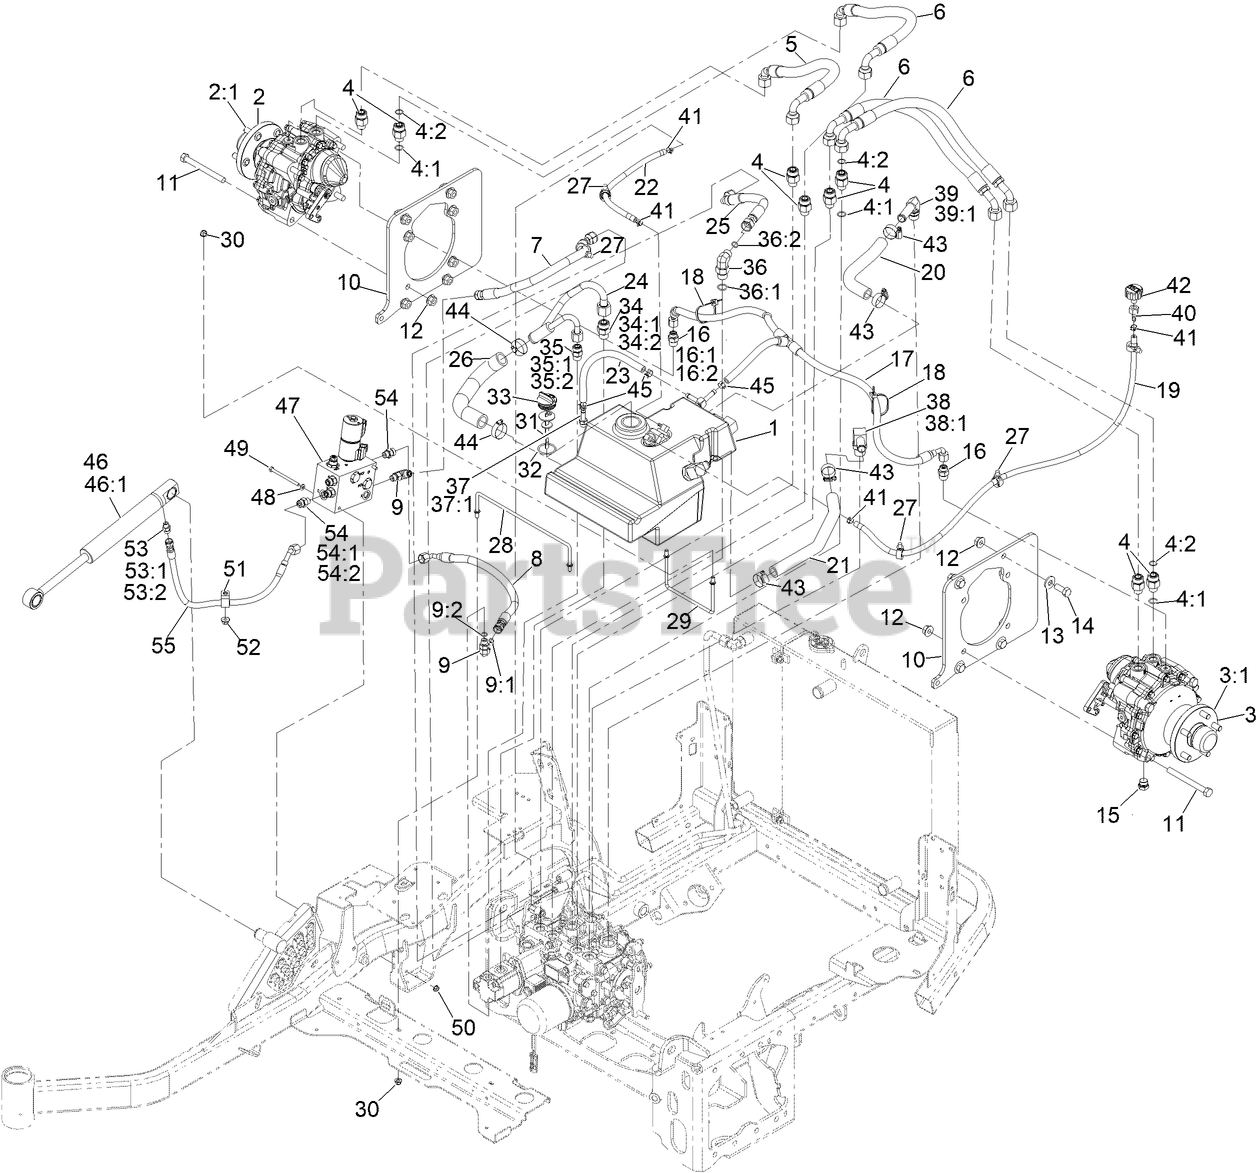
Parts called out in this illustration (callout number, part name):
1	HYD RESERVOIR ASM
2	MOTOR-HYD, RH
2:1	5 STUD WHEEL HUB KIT
3	MOTOR-HYD, LH
3:1	5 STUD WHEEL HUB KIT
4	FITTING-STRAIGHT
4:1	O-RING
4:2	O-RING
5	HOSE ASM
6	HOSE ASM
7	HOSE ASM
8	HOSE ASM
9	FITTING-ELBOW, 90 DEG
9:1	O-RING
9:2	O-RING
10	PLATE-MOTOR
11	SCREW-HH
12	NUT-HHF
13	WASHER-SPRING
14	SCREW-HH
15	PLUG-MAGNETIC
16	FITTING-STRAIGHT
16:1	O-RING
16:2	O-RING
17	TEE HOSE ASM
18	TIE-CABLE
20	HOSE-RETURN
21	HOSE-RETURN
24	TUBE ASM
25	HOSE ASM
26	HOSE-SUCTION
27	CLIP-TIE
28	ROD-SUPPORT, HYD TANK
29	ROD-SUPPORT, HYD TANK
30	NUT-HF, NI
31	DIPSTICK
32	O-RING
33	PLUG-PLASTIC
34	FITTING-STRAIGHT
34:1	O-RING
34:2	O-RING
35	FITTING-STRAIGHT
35:1	O-RING
35:2	O-RING
36	FITTING-ELBOW, 90 DEG
36:1	O-RING
36:2	O-RING
37	ADAPTER-STRAIGHT
37:1	O-RING
38	FITTING-ELBOW, 90
38:1	O-RING
39	FITTING-90
39:1	O-RING
40	FITTING-STRAIGHT
41	CLAMP-HOSE
42	BREATHER
43	CLAMP-HOSE
44	CLAMP-HOSE
45	CLAMP-HOSE
46	CYLINDER-LIFT
46:1	KIT, CYL REPAIR
47	VALVE-LIFT AND HOLD
48	WASHER-FLAT
49	SCREW-HH
50	NUT-HF
51	CLIP-LOOM
52	NUT-HF, NI
53	FITTING-HYD, STRAIGHT
53:1	O-RING
53:2	O-RING
54	FITTING-STRAIGHT
54:1	O-RING
54:2	O-RING
55	HOSE ASM
